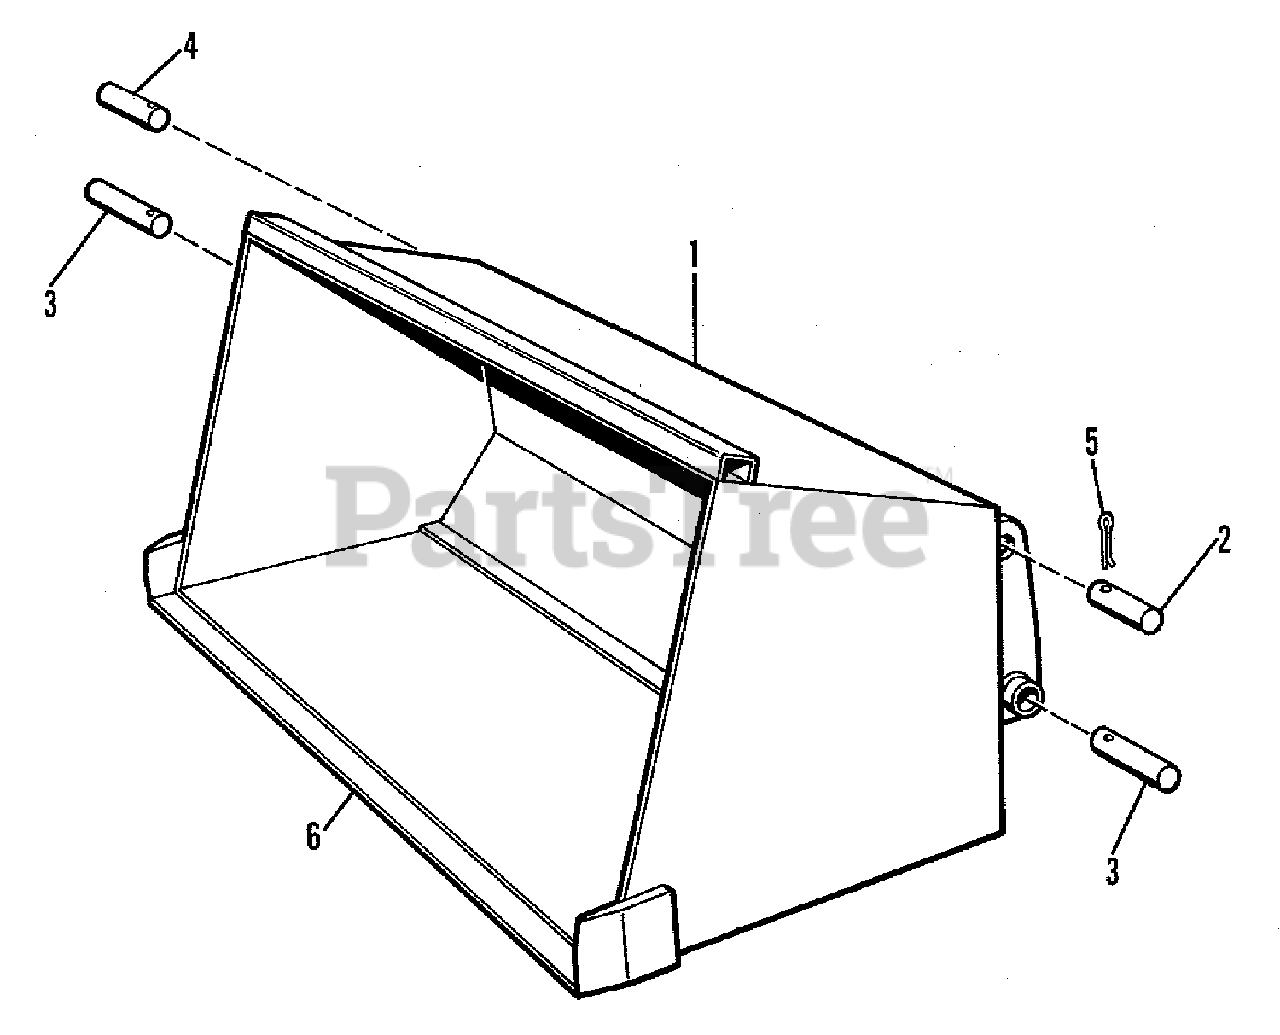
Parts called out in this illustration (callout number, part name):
1	BUCKET ASSEMBLY
2	PIN, Attaching (Upper Left Position)
3	PIN, Attaching (Lower Left & Right Positions)
4	PIN, Attaching (Upper Right Position)
4	FITTING, Lube, 1/4, 90 Degrees
5	PIN, Retaining
6	EDGE, Cutting (Field-Welded for Installation)
